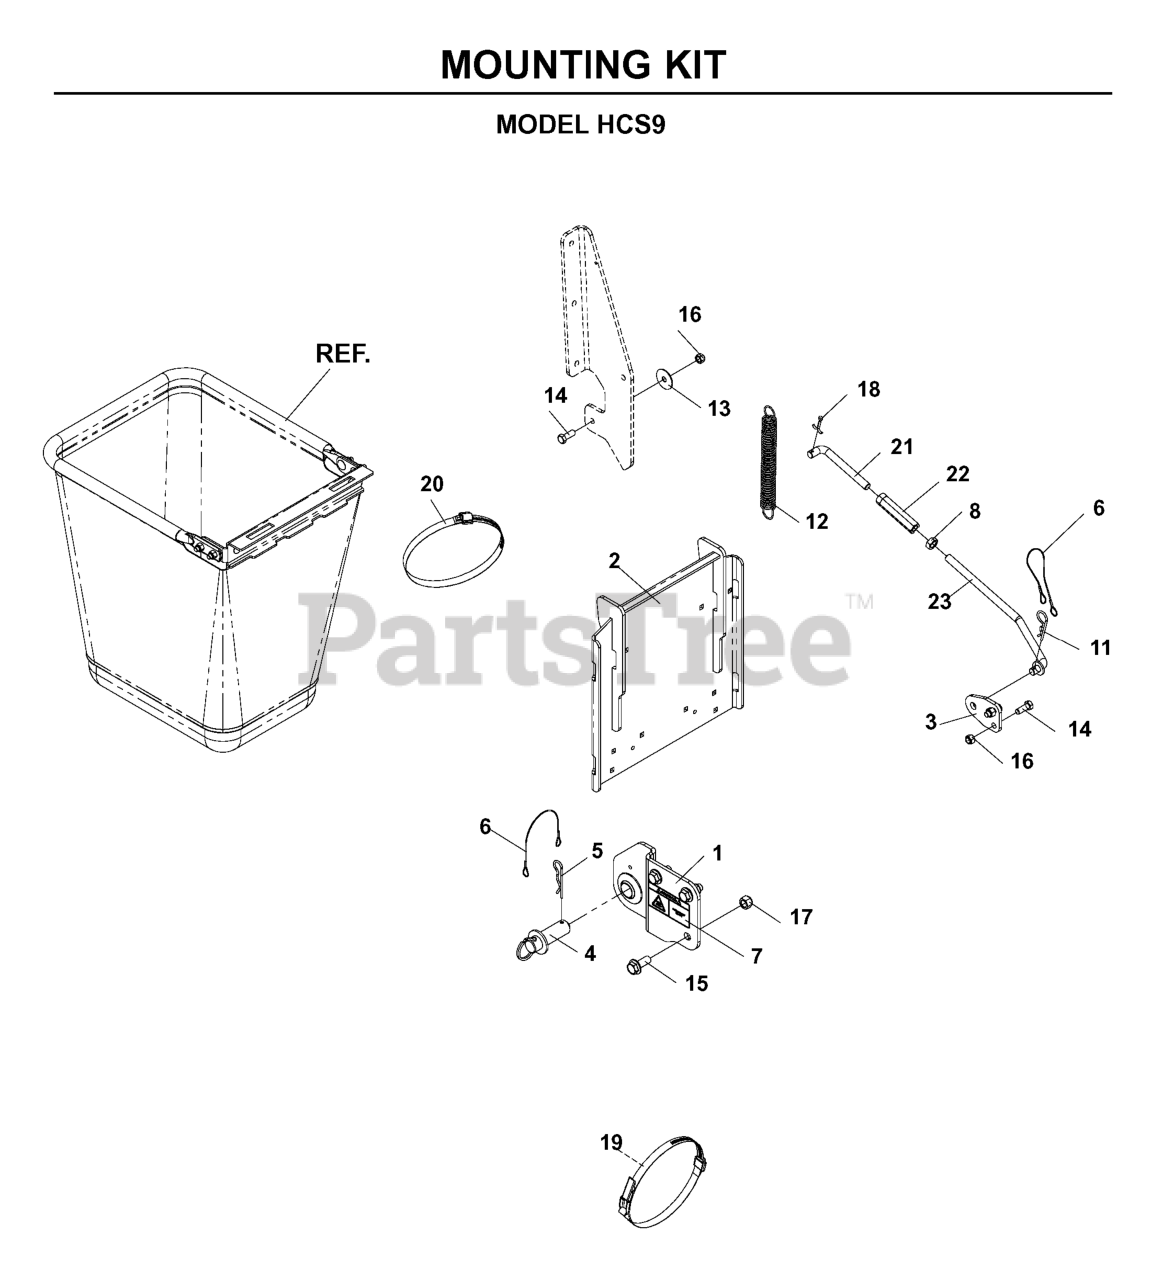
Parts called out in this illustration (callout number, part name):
1	HITCH BRACKET W/ DECAL MID
2	REAR GUARD WELDMENT
3	SUPPORT BRACKET
7	DECAL, HOT SURFACE
8	NUT 1/2-20 HEX JAM ZD
11	HAIRPIN #4
13	WASHER, FRICTION
14	HCS 3/8-16X1.GRD.5.ZD
15	HCS 1/2C X 1 1/4 SERRATED HEAD
16	NUT 3/8-16 NYLOC
17	NUT 1/2-13 HEX NYLOC ZD
18	COTTER PIN
19	OVER CTR BAND
20	HOSE CLAMP 4-1/8 TO 7"
21	SUPPORT LINKAGE, LH
22	TURNBUCKLE, 1/2
23	SUPPORT LINKAGE, MID
539111203	HITCH BRACKET WLD
